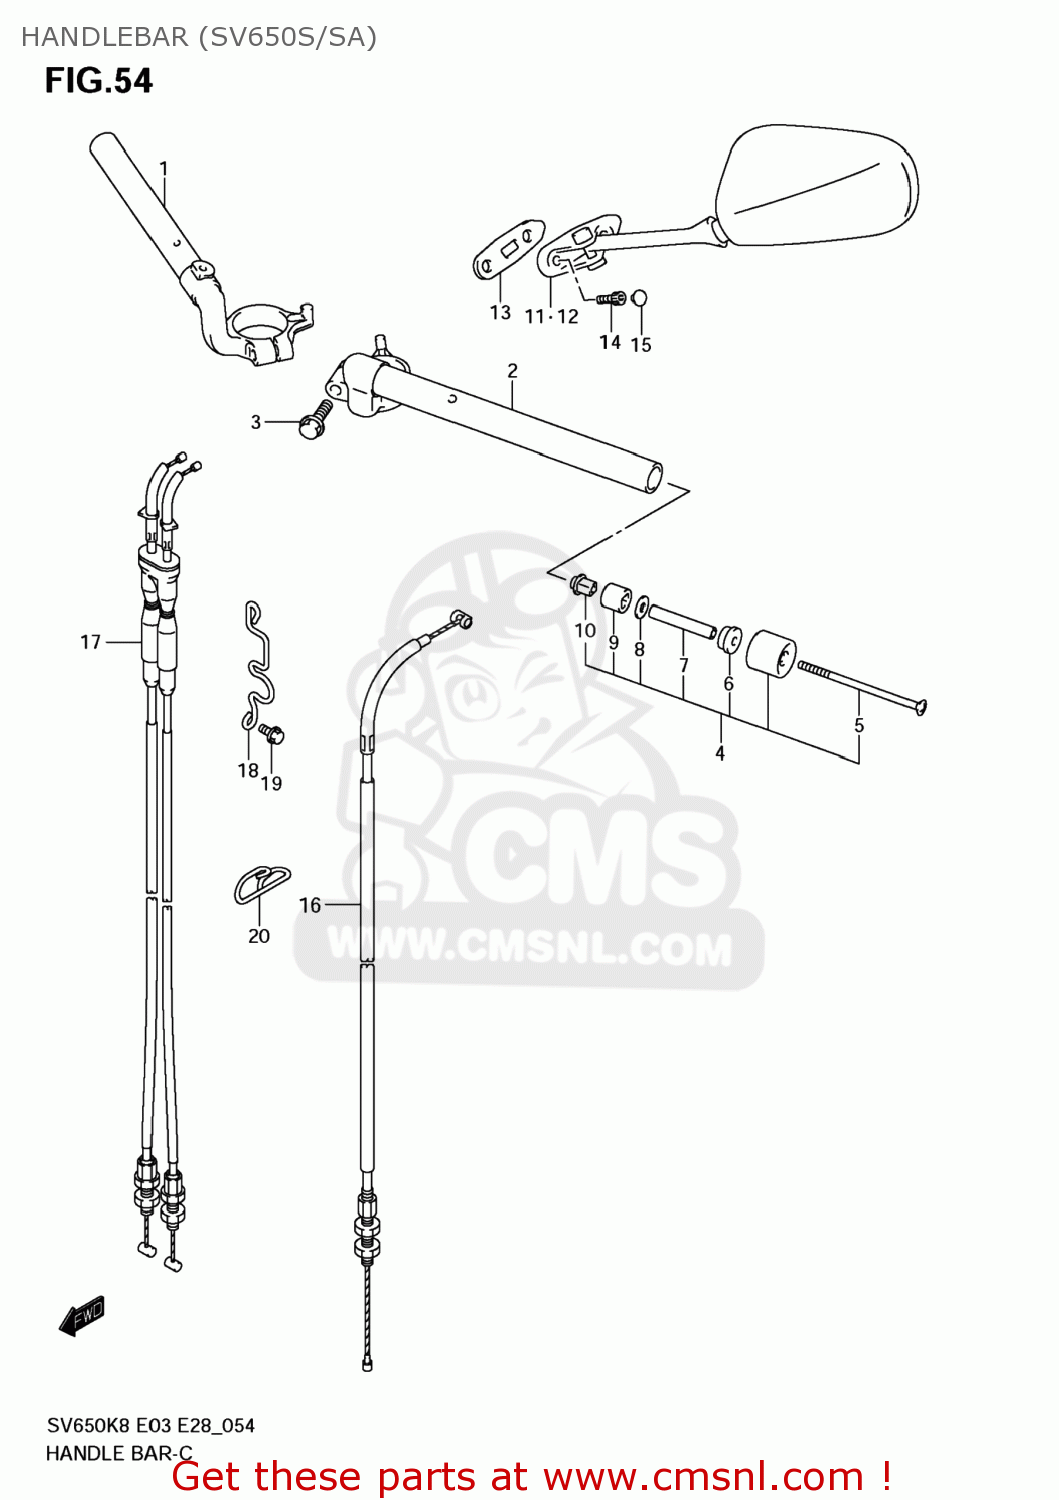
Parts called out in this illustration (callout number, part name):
1	HANDLEBAR,R
2	HANDLEBAR,L
3	BOLT,HANDLEBAR
4	BALANCER SET,HANDLEBAR
5	SCREW
6	EXPANDER,HANDLE BALANCER
7	SPACER,EXPANDER
8	WASHER(6.5X16X1.6)
9	EXPANDER,HANDLE BALANCER
10	NUT,HANDLE BALANCER
11	MIRROR ASSY,RR VIEW,R
12	MIRROR ASSY,RR VIEW,L
13	CUSHION,RR VIEW MIRRORR
14	BOLT
15	CAP(OD:10)
16	CABLE ASSY,CLUTCH
17	CABLE ASSY,THROTTLE
18	GUIDE,CABLE L
19	BOLT
20	GUIDE,THROTTLE CABLE
